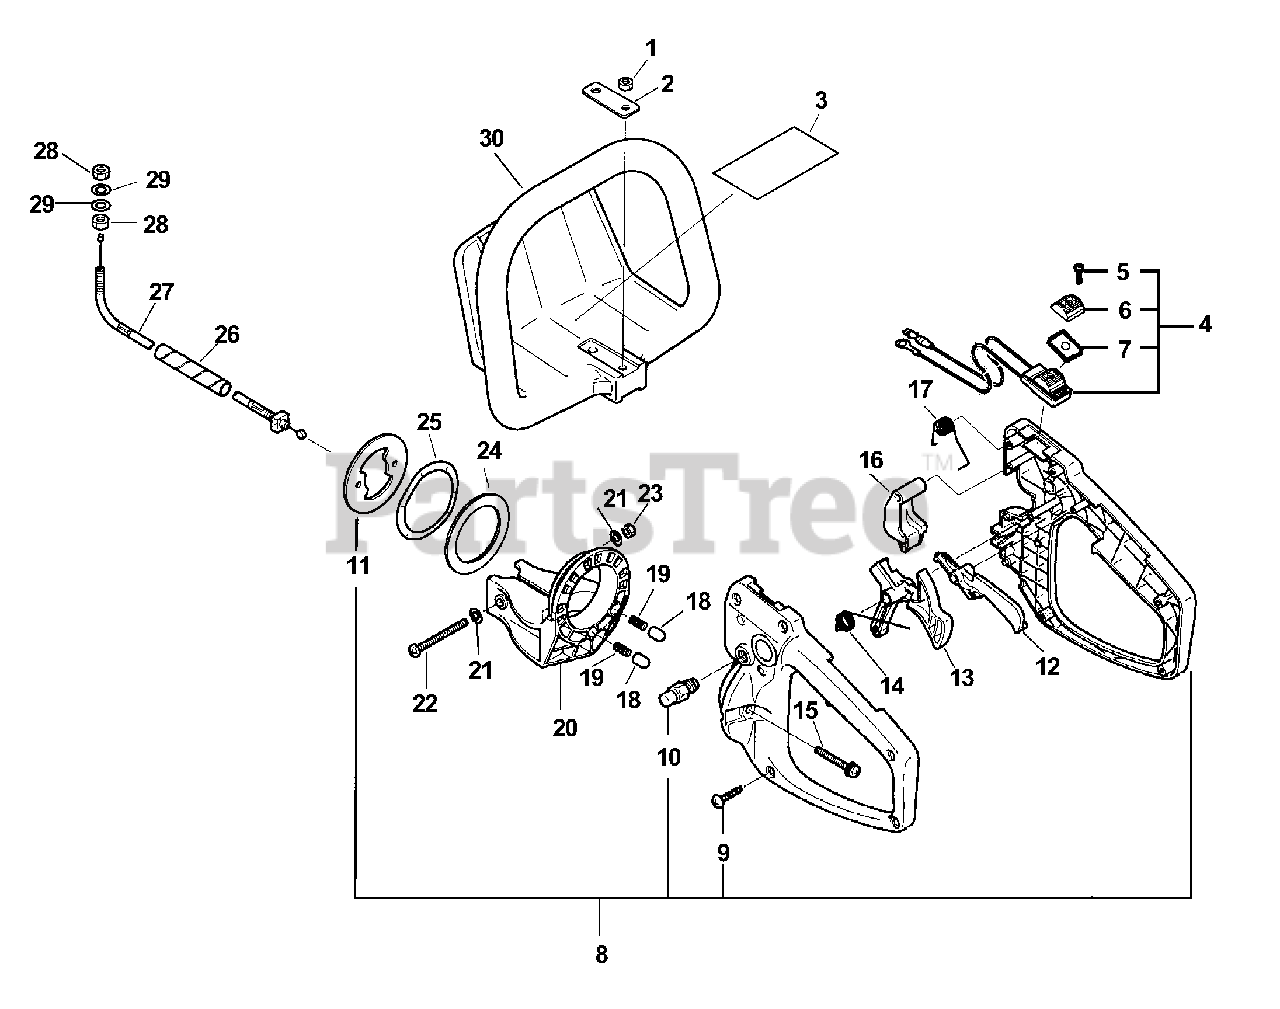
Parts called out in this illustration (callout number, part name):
1	LOCKNUT - 5
3	LABEL - CAUTION
4	IGNITION SWITCH ASSY
5	SCREW - 3X10
6	KNOB, SWITCH - ORANGE
7	COVER, SWITCH - STOP
8	HANDLE ASSY - REAR
9	SCREW - 4X16
10	LOCK, THROTTLE
11	BRACKET, HANDLE
12	LOCKOUT, THROTTLE
13	TRIGGER, THROTTLE
15	SCREW - 5X30
17	SPRING, TRIGGER
19	SPRING, TRIGGER
20	BRACKET, HANDLE
21	WASHER - 5
22	SCREW - 5X40
23	LOCKNUT - 5
24	WASHER - 50
25	WASHER
27	CABLE, THROTTLE
29	WASHER - 6
30	HANDLE - FRONT
